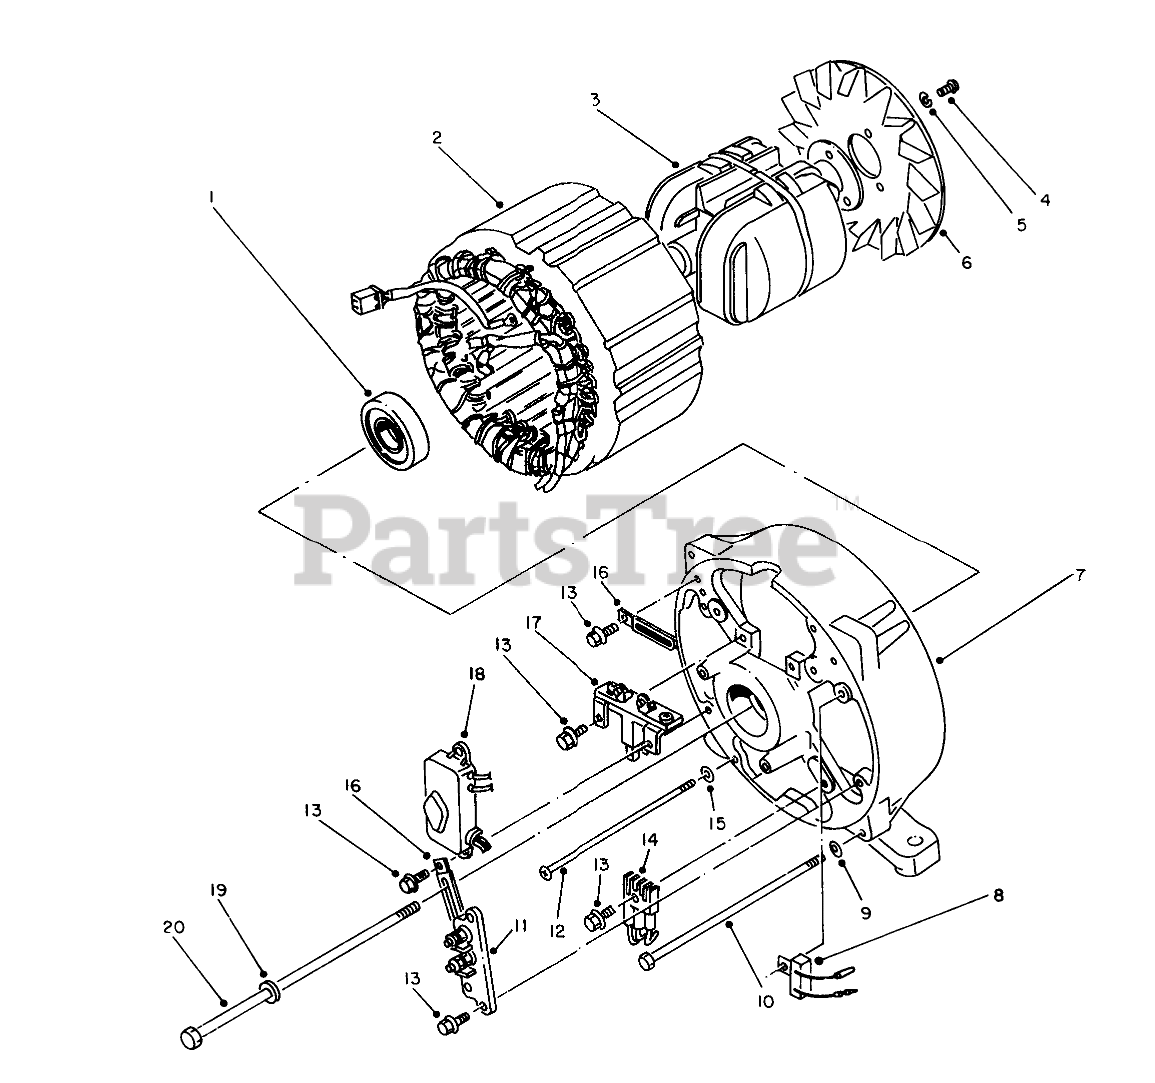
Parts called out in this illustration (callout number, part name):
1	Bearing
2	Stator
3	Rotor
4	SCREW
5	Washer
7	Bracket-Rear
8	Register
9	Washer
10	BOLT (6X171)
11	Terminal
12	Screw
14	Diode
15	WASHER
16	Clamp
17	Holder-Brush
18	Regulator-Voltage
19	Washer
